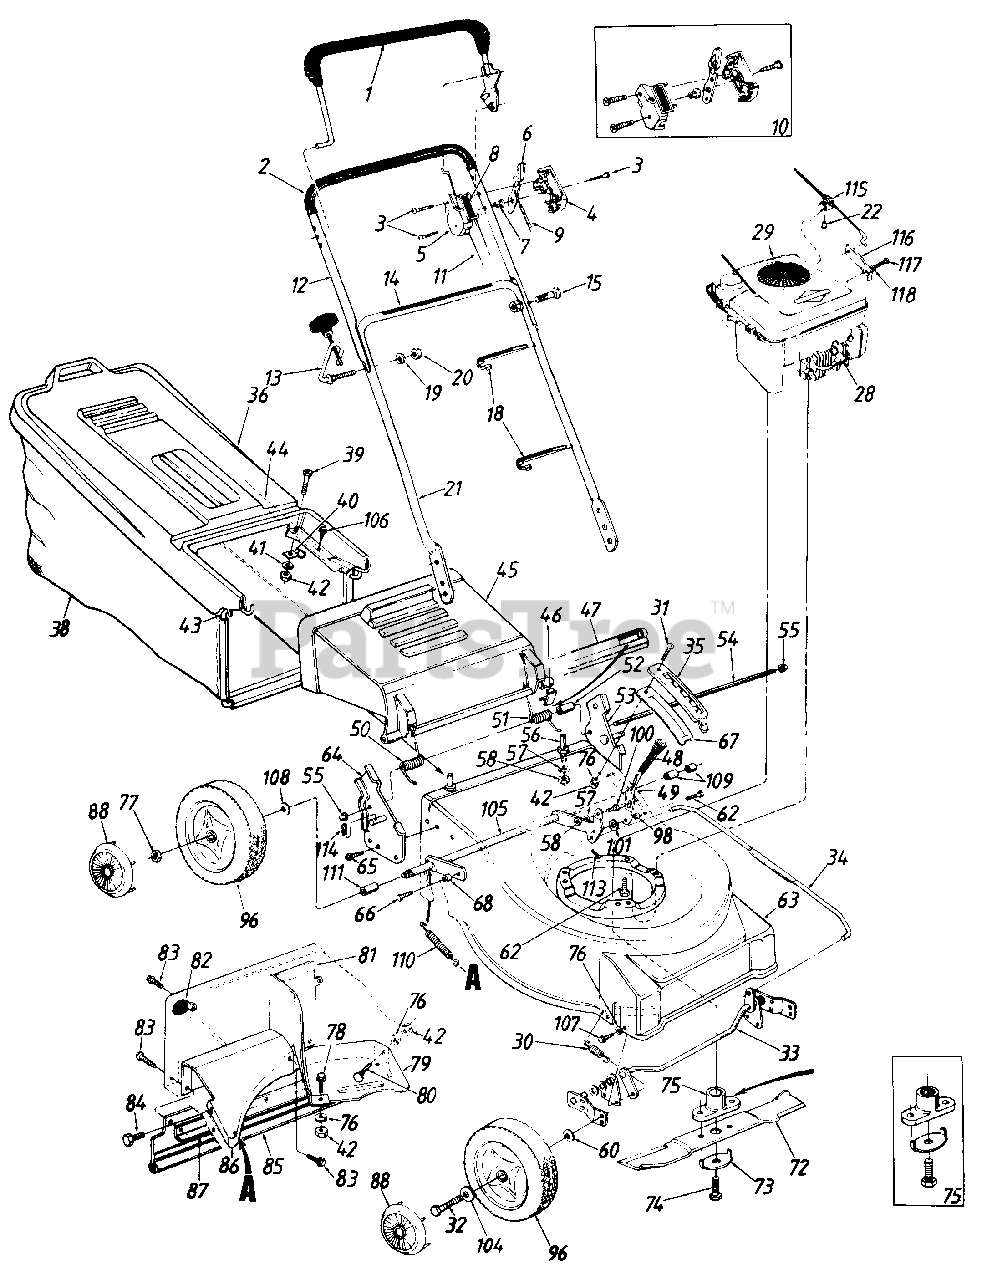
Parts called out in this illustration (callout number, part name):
1	Control Handle Ass'y.
3	Truss Mach. B-Tap Scr. #12 x 1.5" Lg.
4	Control Panel Half
5	Clutch Panel Half
6	Throttle Control Lever
7	Control Disc Pin
8	Control Label-Throttle
9	Throttle Wire-53" Lg.
10	Control Housing Comp.
11	Control Cable-46" Lg.
12	Upper Handle
13	Rope Guide Bolt
14	Instruction Label-Handle
15	Curved Carriage Bolt 5/16-18 x 1.38" Lg.
18	Cable Tie
19	L-Wash. 5/16" I.D.
20	Hex Nut 5/16-18 Thd.
22	POP Rivet 156" Dia. x .379"
28	Spark Plug Boot
29	Engine
30	Extension Spring 2.39" Lg.
31	Truss Mach. Scr. 1/4-20 x .62" Lg.
32	Axle Bolt
33	Front Axle Ass'y.
34	Height Adj. Connecting Rod
35	Height Adjustment Plate
36	Hardtop Bag Cover
38	Grass Bag
39	Truss Mach. Scr. 1/4-20 x 1.0" Lg.
40	Hardtop Mounting Clip
41	Fl-Wash. .281" l.D. x .62' O.D.
42	Hex Nut 1/4-20 Thd.
43	Front Catcher Frame
44	Rear Catcher Frame
45	Chute Deflector
46	Deflector Plug
47	Seal-Extrusion
49	Spring Lever
50	Torsion Spring-R.H.
51	Torsion Spring-L.H.
52	Spacer .255" I.D.
53	Handle Brkt. Ass'y.-L.H.
54	Hinge Pin 17.75" Lg.
55	Cap Speed Nut
56	Shld. Pin 3/8-24 x 1.43" Lg.
57	L-Wash. 3/8" I.D.
58	Hex Jam Nut 3/8-24 Thd.
60	Bell-Wash. .38" l.D. x .88" O.D.
62	Hex L-Wash. Hd. Scr. 3/8-16 x l" Lg.
63	21" Deck Ass'y.
64	Handle Brkt. Ass'y.-R.H.
65	Hex L-Wash. Hd. AB-Tap Scr. 1/4 x.62" Lg.
66	Hex Wash. Hd. Tap Scr. 3/8-16 x .75" Lg.
67	Height Adjustment Support
68	Spacer .385" I.D.
72	21" Blade
73	Blade Bell-Wash. .44" I.D. x 2.38"
74	Hex Bolt 7/16-20 x 1.5" Lg.
75	Blade Adapter Kit
76	L-Wash. 1/4" l.D.
77	Hex Jam Nut 1/2-20 Thd.
78	Hex Bolt 1/4-20 x .85" Lg.
79	Rear Belt Baffle
80	Carr. Bolt 1/4-20 x .50" Lg.
81	Rear Panel Baffle
82	Corner Plug
83	Torx Mach. AB-Tap Scr. 1/4 x .62" Lg.
84	Hex B-Tap Scr. 1/4 x .38" Lg.
85	Rear Flap
86	Rear Chute Baffle
87	Retaining Strip
88	Hub Cap (8 x 1.75)
88	Hub Cap (8 x 2)
96	Wheel Ass'y. (8 x 1.75)
96	Wheel Ass'y. (8 x 2)
98	Shld. Spacer .50" Dia.
100	Shld. Pin 3/8-24 x 1.43" Lg.
101	Fl-Wash. .375" l.D. x 1.0"
104	Fl-Wash. .531" l.D. x .93"
105	Rear Axle Ass'y.
106	Hex AB-Tap Scr. 1/4" x .62 Lg.
107	Hex L-Wash. HD AB-Tap Scr. 1/4 x.38" Lg.
108	Fl-Wash. .510" l.D. x .75" O.D.
109	Spacer.526" l.D.
110	Extension Spring 3.8" Lg.
111	Sleeve.526n l.D.
113	Cotter Pin 3/32" Dia. x .75"
114	Internal Cotter Pin 5/16" Dia.
115	Cable Mtg. Brkt.
116	Mounting Brkt.
117	Truss Mach. Scr. #10 x .5" Lg.
118	L-Wash. #10 I.D.
